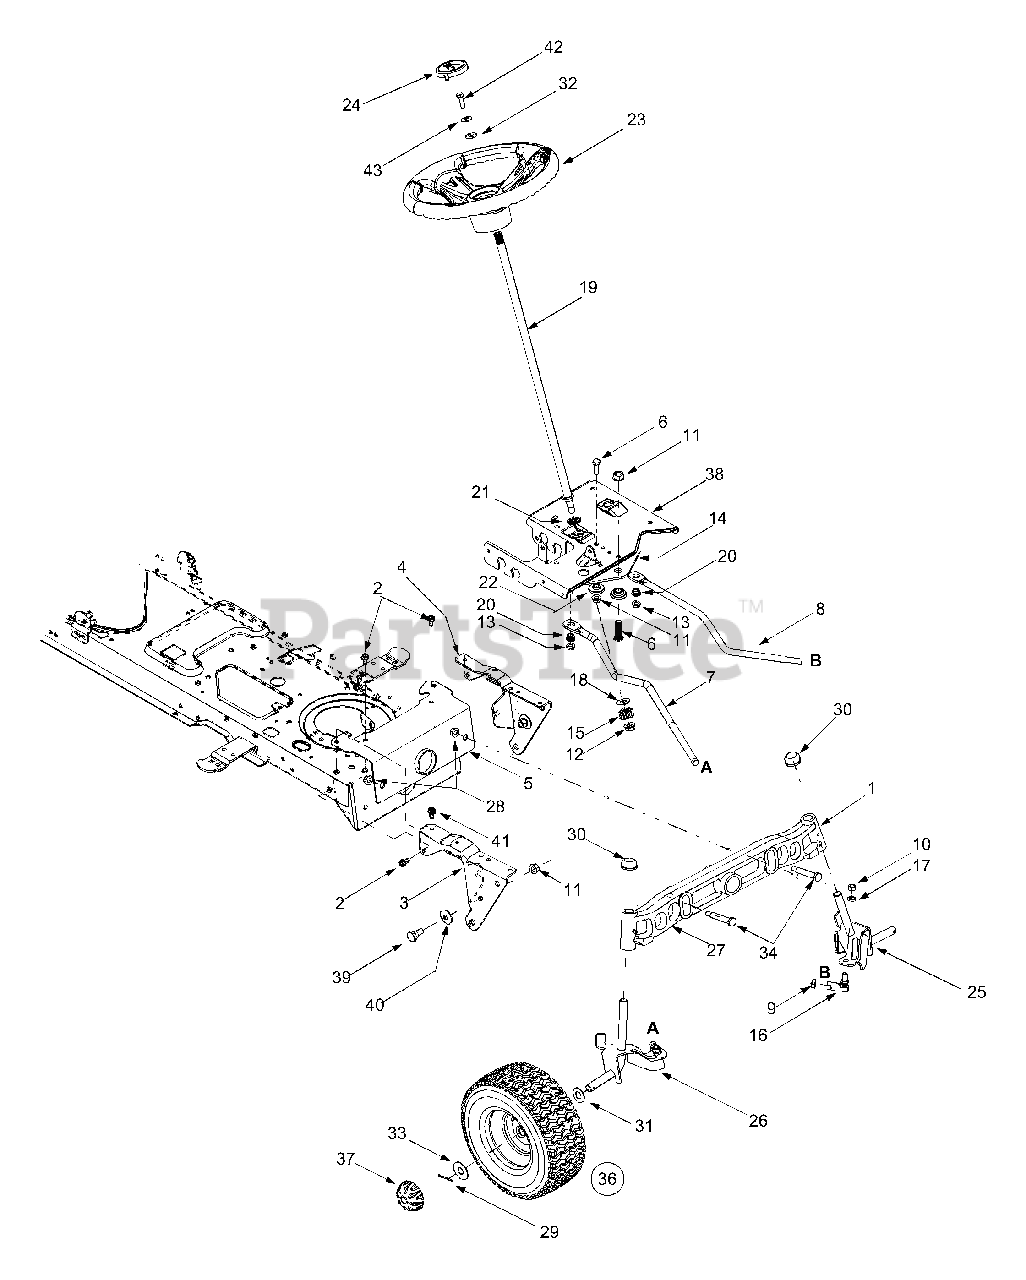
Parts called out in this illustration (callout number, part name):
1	Pivot Bar: Axle
2	Self-tapping Screw, 16-18 x .625
6	Hex Cap Screw, 3/8-16 x 1.25
7	RH Drag Link
8	LH Drag Link
9	Jam Nut, 7/16-20
10	Hex Nut, 3/8-24
11	Lock Nut, 3/8-16
12	Flange Lock Nut, 7/16-20
13	Lock Nut, 5/16-18
14	Steering Gear, 11/90 Ratio
15	Steering Pinion Gear
16	Ball Joint, 7/16-20
18	Flat Washer, .51 x 1.12 x .06
19	Steering Shaft, .625 OD x 24.4
20	Plastic Bushing, .38 ID
21	Hex Flange Bearing, 5/8
22	Shoulder Spacer, .38 ID
23	Steering Wheel
24	Steering Wheel Cap, Round
25	LH Axle Assembly, .750 Diameter
26	RH Axle Assembly, .750 Diamet
27	Steel Pivot Bar
28	Lock Nut, 3/8-16
29	Cotter Pin
30	Push Cap, .625
31	Flat Washer, .64 x 1.0 x .12
32	Flat Washer, .406 x .875 x .105
33	Flat Washer, .635 x 1.589 x .06
34	Shoulder Screw, .5 x 2.2, 3/8-16
37	Deluxe Hub Cap
39	Shoulder Screw, 3/8-16
40	Bell Washer, .39 x 1.13 x .062
41	Self-tapping Screw, 5/16-18 x .75
42	Hex Bolt, 5/16-18 X 1
43	Bell Washer
